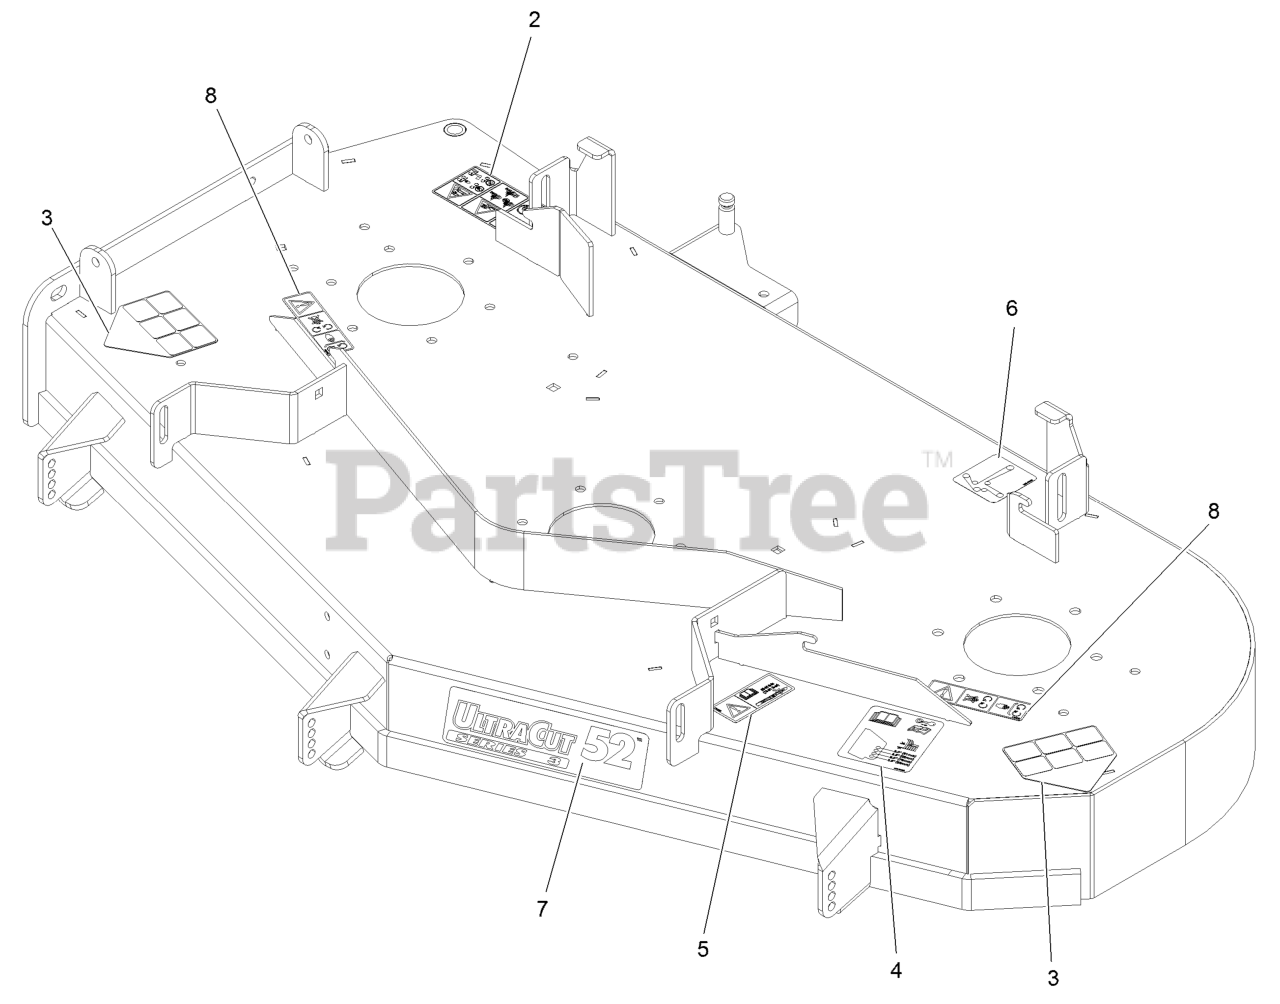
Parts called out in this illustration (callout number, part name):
2	DECAL-DANGER
3	DECAL-DANGER
4	DECAL-ROLLER, ANTI-SCALP
5	DECAL-BOLT TORQUE
6	DECAL-ROUTING, BELT
7	DECAL-ULTRACUT 52 SERIES
8	DECAL-COVER, MISSING
